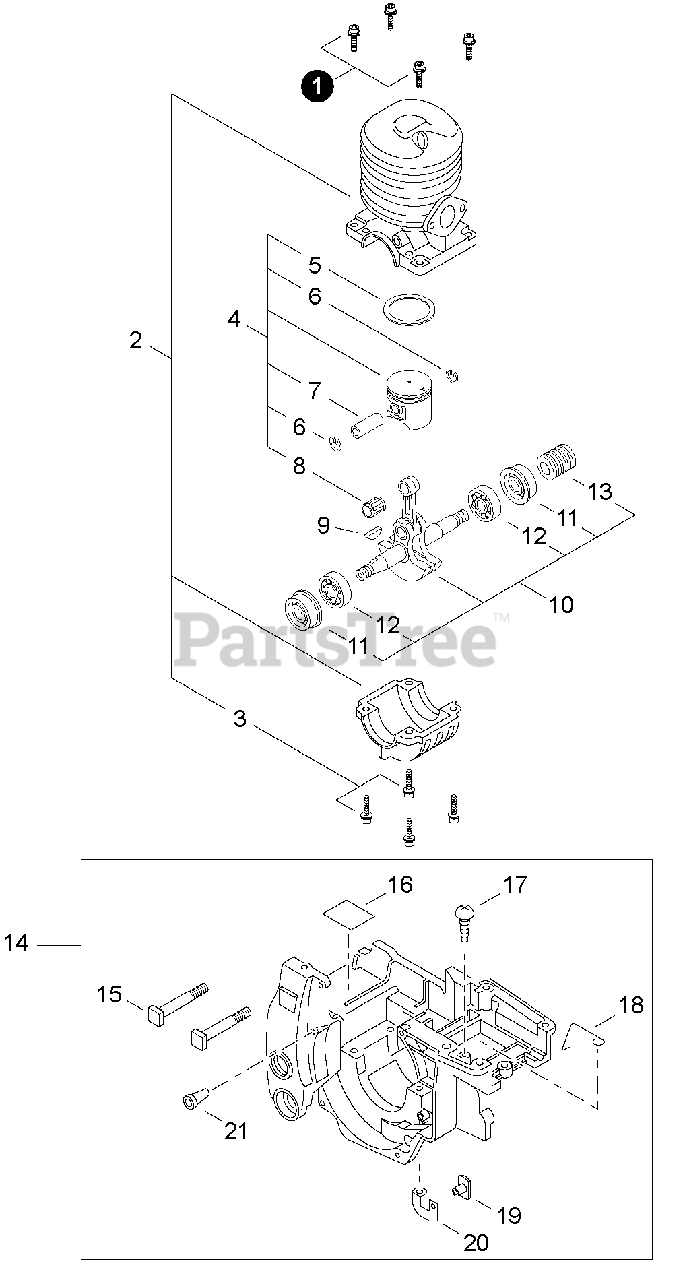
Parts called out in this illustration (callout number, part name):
1	BOLT 5×30
2	CRANKCASE KIT
3	BOLT 5×22
4	PISTON KIT
5	RING, PISTON
6	RING, SNAP
7	PIN, PISTON
8	BEARING, NEEDLE 9
9	KEY, WOODRUFF
10	CRANKSHAFT ASSY
11	SEAL, OIL 12
12	BEARING, BALL 6201
13	GEAR, WORM
14	HOUSING ASSY, ENGINE
15	STUD, GUIDE BAR 8
16	SHIELD, HEAT
17	SCREW 4×8
18	WIRE
20	PLATE, GROUND
21	VENT ASSY
